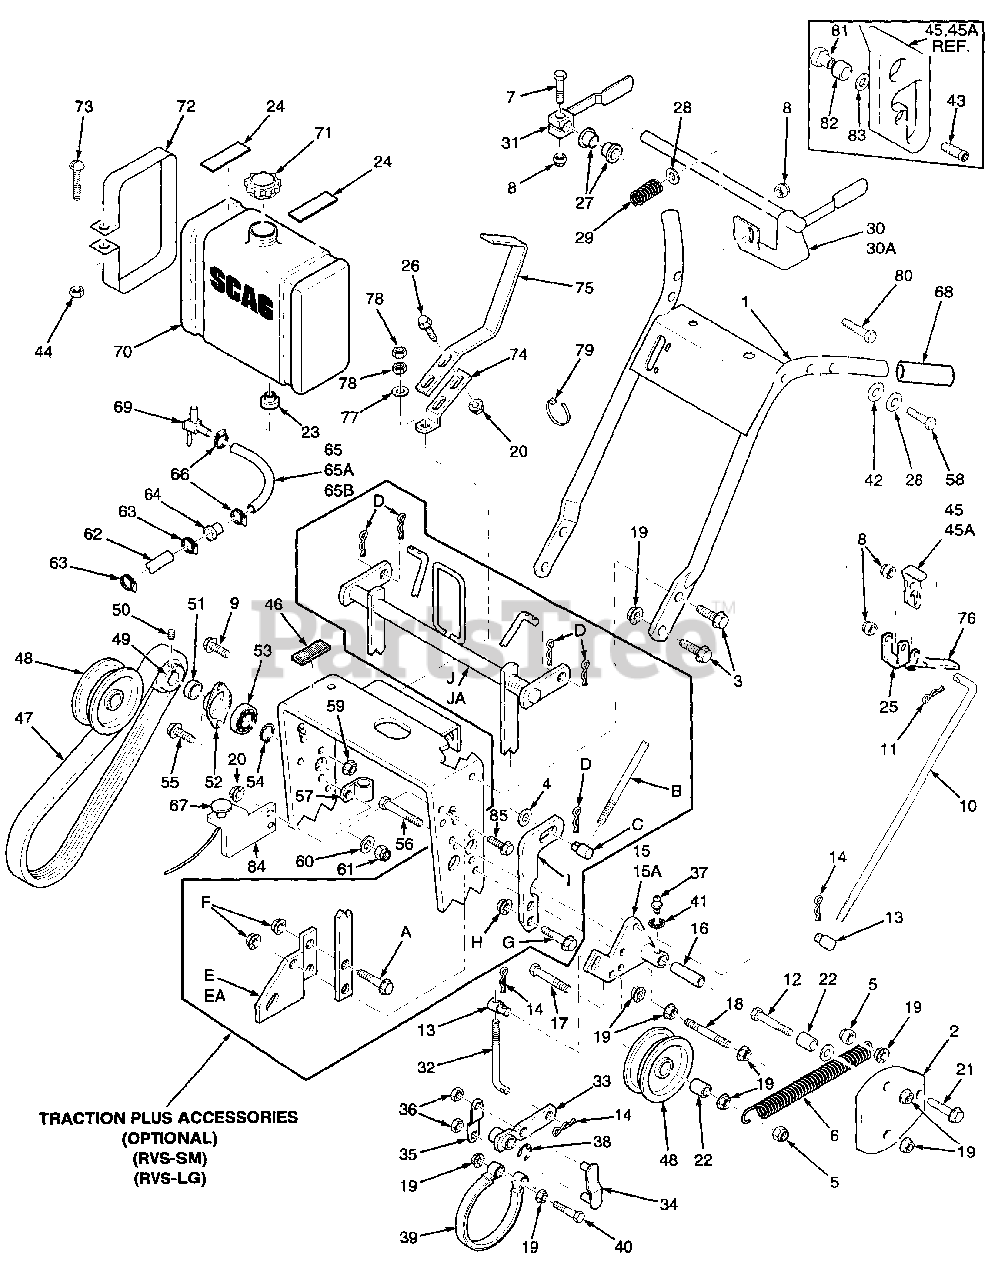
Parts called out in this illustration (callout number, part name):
1	Handle Assembly
2	Belt Guard
3	Capscrw, 3/8 - 16 x 1" Ser. Flange
4	Washer, 3/8" (.391 x .938 x .105)
5	Nut, 3/8 - 16 Elastic Stop
6	Spring, Idler
7	Bolt, 5/16 - 18 x 1 - 1/4" Hex Head
8	Nut, 5/16 - 18 Elastic Stop
9	Capscrew, 1/4 - 20 x 3/4" Hex Head
10	Control Rod, Steering
11	Hair Pin, Small
12	Bolt, 3/8 - 16 x 4 - 1/2" Hex Head
13	Swivel Joint
14	Hair Pin, Large .094 Diameter
15	Idler Bracket, RH
15A	Idler Bracket, LH
16	Idler Sleeve
17	Bolt, 3/8 - 16 x 3/4" Hex Head
18	Support Belt Guard
19	Nut, 3/8 - 16 Serrated Flange
20	Nut, 5/16 - 18 Serrated Flange
21	Cpscrw, 3/16 - 18 x 1 - 1/4" Ser. Flng.
22	Spacer
23	Bushing
24	Rubber Pad, (Upper)
25	Steering Lever
26	Capscrew, 5/16 - 18 x 1" Ser. Flng.
27	Bushing
28	Washer, 5/16 (.375 x .875 x .083)
29	Spring, Operator Presence
30	Operator Presence Lever, LH (Small Frame)
30A	Operator Presence Lever, LH (Large Frame)
31	Operator Presence Lever, RH
32	Brake Rod
33	Brake Lever
34	Brake Link
35	Brake Link Plate
36	Nut, 3/8 Push - on
37	Greese Fitting, Straight 1/4 - 28
38	Retaining Ring, 5/8 Ext. "E"
39	Brake Band
40	Bolt, 3/8 - 16 x 2" Hex Head
41	1/4" Internal Tooth Lockwasher
42	Curved Spring Washer
43	Socket Head Capscrew #8 - 32 x 1/2"
44	Nut, 1/4 - 20 Hex
45	Neutral Latch, RH
45A	Neutral Latch, LH
46	Rubber Pad (Lower)
47	Belt, Wheel Drive
48	Idler Pulley, Wheel Drive
49	Pulley, Jackshaft
50	Setscrew, Hex Socket Knurl Cup Pt. 5/16 - 18 (nylock)
51	Spacer, Jackshaft Pulley
52	Flange, Jackshaft Bearing
53	Bearing, Jackshaft
54	Retaining Ring, 5/8 Ext. Basic
55	Capscrew, 1/4 - 20 x 1" Ser. Flange
56	Bolt, 1/4-20 x 6" Carriage
58	Bolt, 5/16 - 18 x 2" Hex Head
59	Nut, 1/4 - 20 Serrated Flange
60	Flatwasher, 5/16 (.375 x .875 x .083)
61	Nut, 1/4 - 20 Elastic Stop
62	Fuel Hose
63	Fuel Hose Clamp
64	Not used on this model
65B	Fuel Hose, 1/4" ID, 23"
66	Clamp, Fuel Hose
67	Choke Control
68	Grip, Handle
69	Valve, Fuel Shut Off
70	Fuel Tank Assy.
71	Fuel Tank Cap
72	Strap, Fuel Tank
73	Screw, 1/4 - 20 x 2" Round Hd Slotted
74	Shift Lever
75	Shift Lever Extention
76	Grip, Steering Lever
77	Washer, 3/8 (.391 x .938 x .105)
78	Nut, 3/8 - 24 UNF
79	Cable Tie
80	Bolt, 5/16 - 18 x 2 - 1/2"
81	Bushing, Bearing Retainer
82	Bearing
83	Washer, #8 - .170 x .375 x .032
84	Bracket, Choke Mounting
85	Capscrew, 5/16 - 18 x 1" Ser. Flng.
A	Capscrew, 3/8 - 16 x 1" Ser. Flng.
B	Rod, Traction Control
C	Swivel Joint
D	Hair Pin, Large .094 Dia
E	Mounting Brkt. LH Traction Cont.
EA	Mounting Brkt. RH Traction Cont.
F	Nut, 3/8 - 16 Serrated Flange
G	Capscrew, 5/16 - 18 x 3/4" Ser. Flg.
H	Nut, 5/16 - 18 Serrated Flange
I	Traction Lever, LH
J	Traction Lever Wldmnt. (Small Fm.)
JA	Traction Lever Wldmnt. (Large Fm.)
